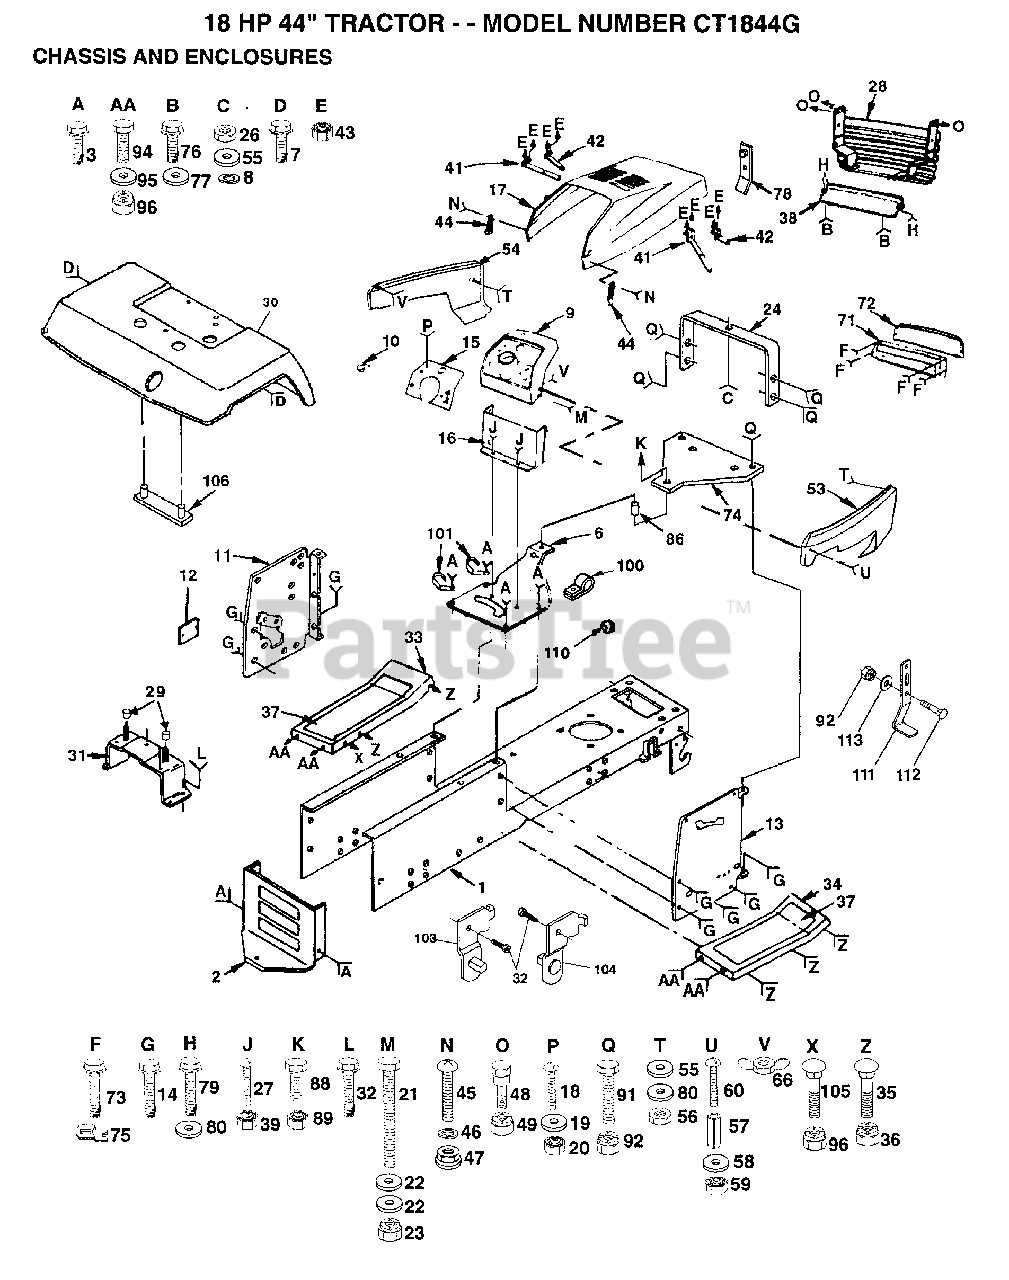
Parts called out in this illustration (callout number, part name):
2	DRAW BAR
3	SCREW
7	SCREW LT
8	LOCKWASHER
9	DASHBOARD BLACK
10	PLUG-DASH T
11	PANEL.DASH.LH
12	COVER ACCESS
13	PANEL.DASH.RH
14	SCREW
15	PLATE SLKSCR YP
16	LOWER DASH
18	SCREW
19	WASHER
21	BOLT
22	WASHER
24	SUPPORT ASS'Y
27	SCREW
29	NUT-PUSH YT
30	FENDER.RALLY.GRN.
31	BRKT.ASM.FENDER
32	SCREW
35	BOLT
36	NUT
37	FOOTREST PAD
38	"STRAP,GRILL "
43	NUT
44	HOOD LATCH T
45	SCREW
46	LOCKWASHER
47	WELDNUT
53	PANEL SIDE RH ASM
54	PANEL SIDE LH ASM
55	WASHER PM
57	SPACER LT
58	WASHER
60	SCREW
72	LENS LT
74	PLATE.SUPT.BATTER
75	"""J"" FASTENER LT"
76	SCREW
77	WASHER
79	SCREW HEX CRT
80	WASHER
86	SPACER
88	BOLT
89	NUT
91	BOLT
92	NUT
94	BOLT
95	WASHER
96	NUT
100	CLIP T
101	"CLIP,INSULATOR"
103	BRACKET ASM LH
104	BRACKET ASM RH
106	STRAP ASM FENDER
111	STOP.OVER.CENTER
112	BOLT
113	WASHER GT
